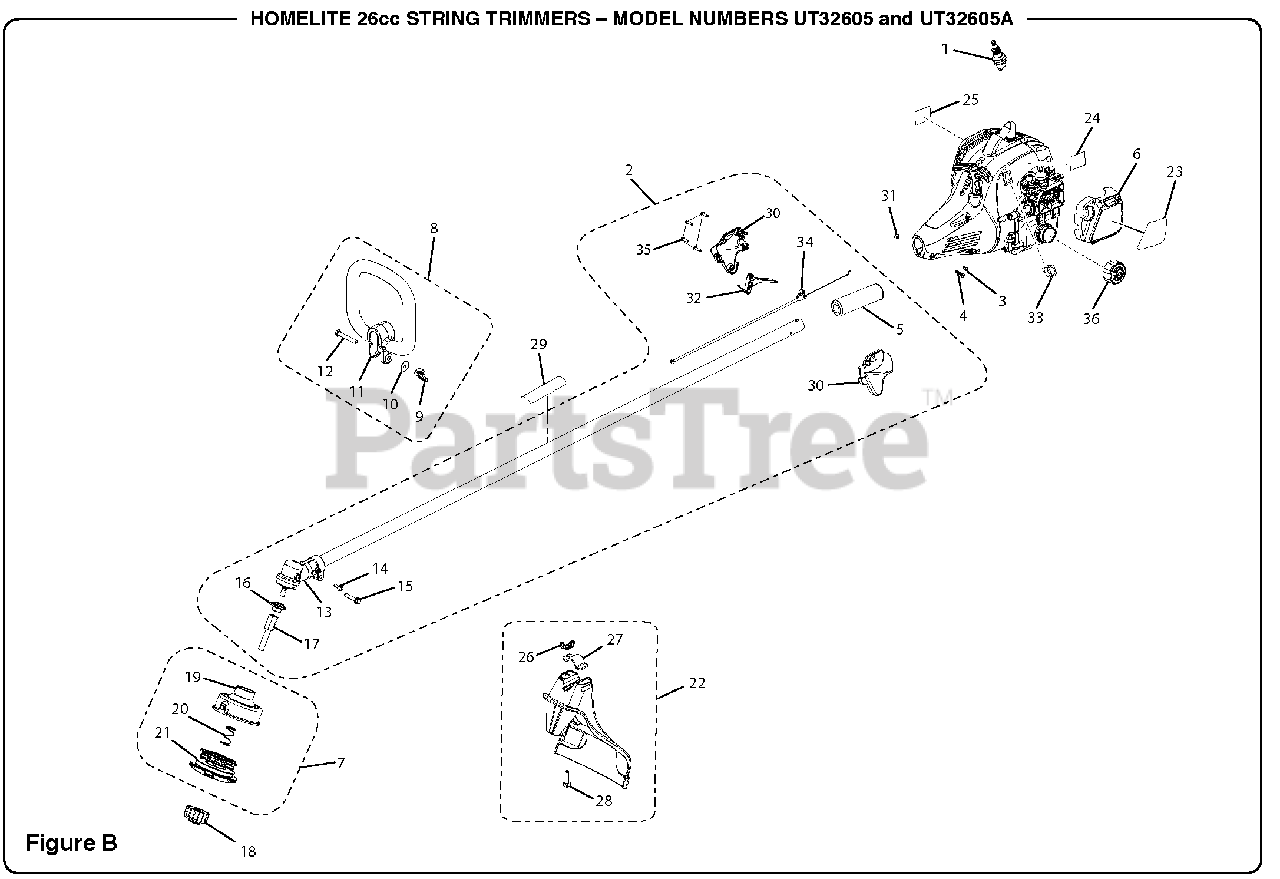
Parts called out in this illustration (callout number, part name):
1	Spark Plug (Champion RCJ6Y)
2	Boom Assembly
3	Screw (8-16 x 5/16 in.)
4	Screw (M6 x 20 mm)
5	Foam Grip
6	Air Box Cover
7	String Head Assembly
8	Front Handle Assembly
9	Wing Nut (1/4-20)
11	Front Handle
12	Bolt (1/4-20 x 2 in.)
13	Gear Head
14	Screw (10-25 x 5/16 in.)
15	Screw (1/4-20 x 1.25 in.)
16	Flange Washer
17	Adaptor
18	Spool Retainer
19	String Head Housing
20	Spring
21	Spool
22	Grass Deflector Assembly
23	Starting Label
24	Model Label (26SS)
25	Combustion Warning Label
26	Wing Nut (1/4-20)
28	Bolt (Square Head)
29	Icon Warning Label
30	Handle Assembly
31	Hex Nut (M6)
32	Throttle Trigger
33	Momentary Stop Switch
34	Throttle Cable
35	Screw (M4 x 20 mm)
